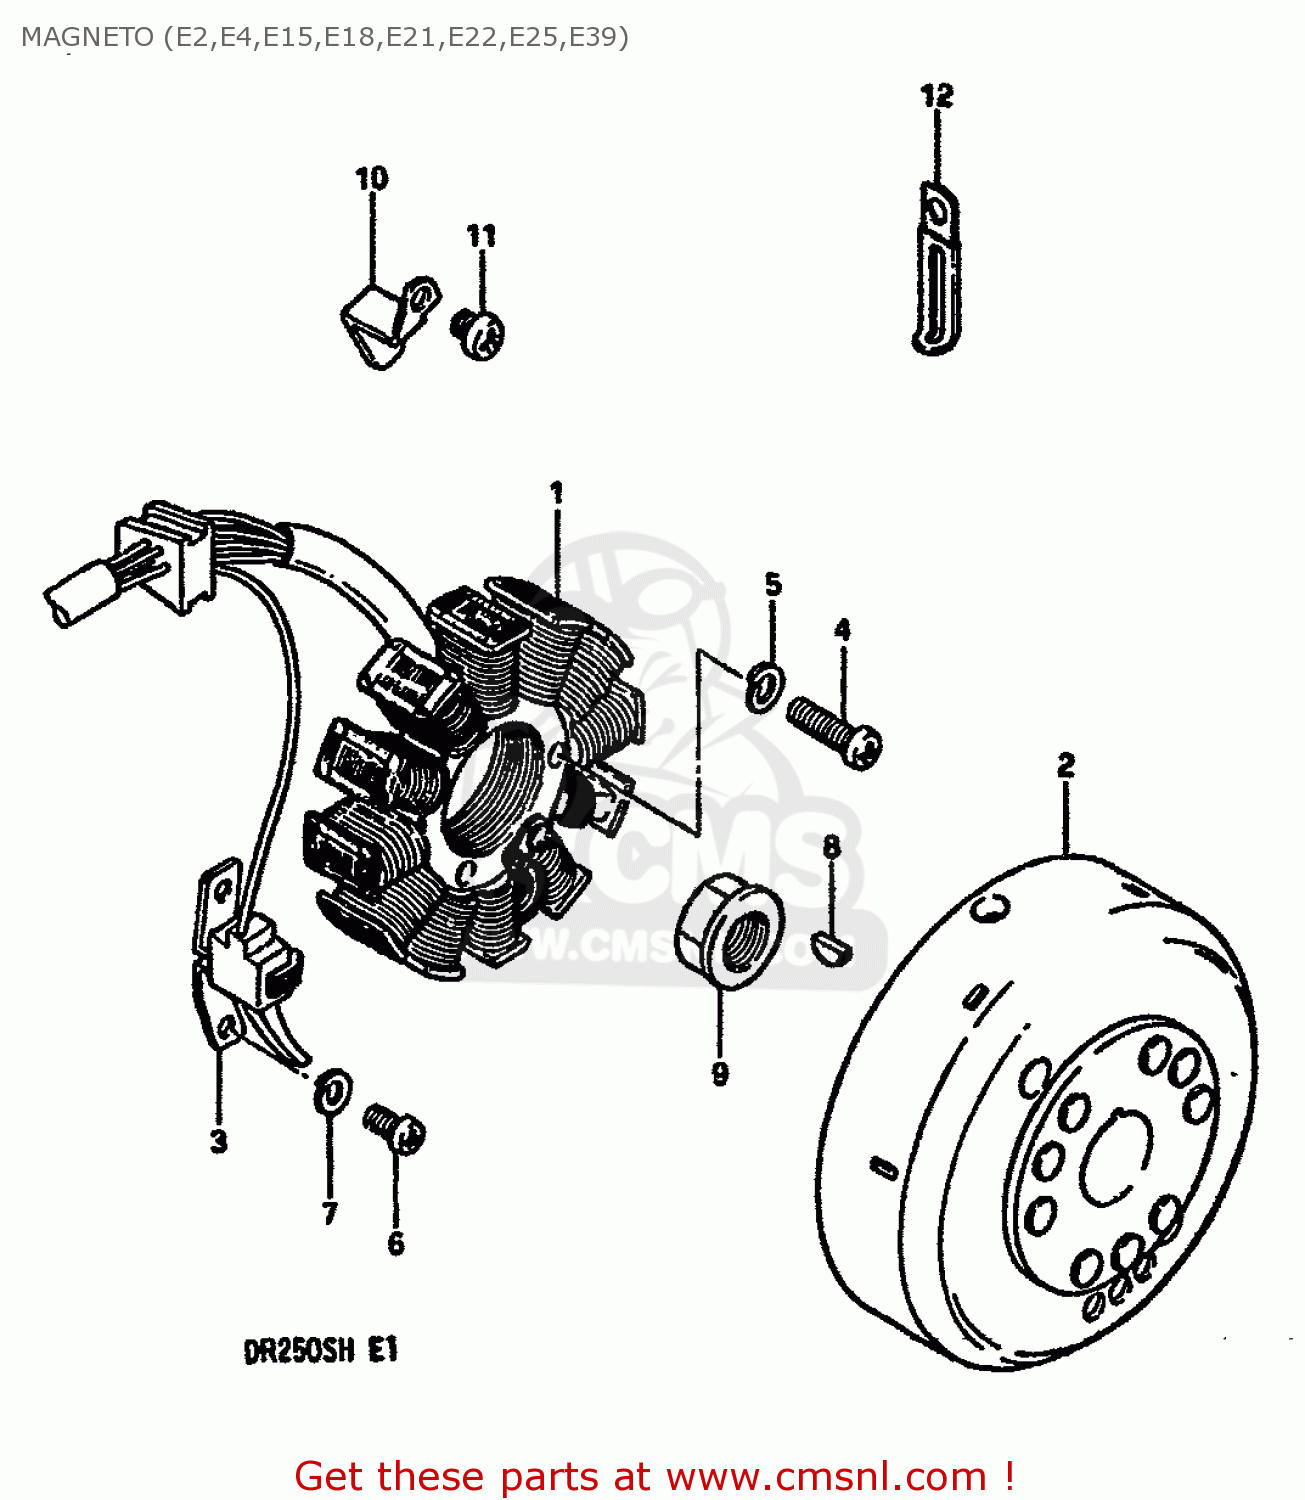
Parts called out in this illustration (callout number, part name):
1	STATOR ASSY
2	COIL,PICK UP
3	ROTOR, FLYWHEEL
4	SCREW
5	WASHER,LOCK
6	SCREW
7	LOCK WASHER
8	KEY 4MM
9	NUT,GENERATOR ROTOR
10	CLAMP,MAGNETO LEAD WIRE
11	SCREW
12	CLAMP L:35
